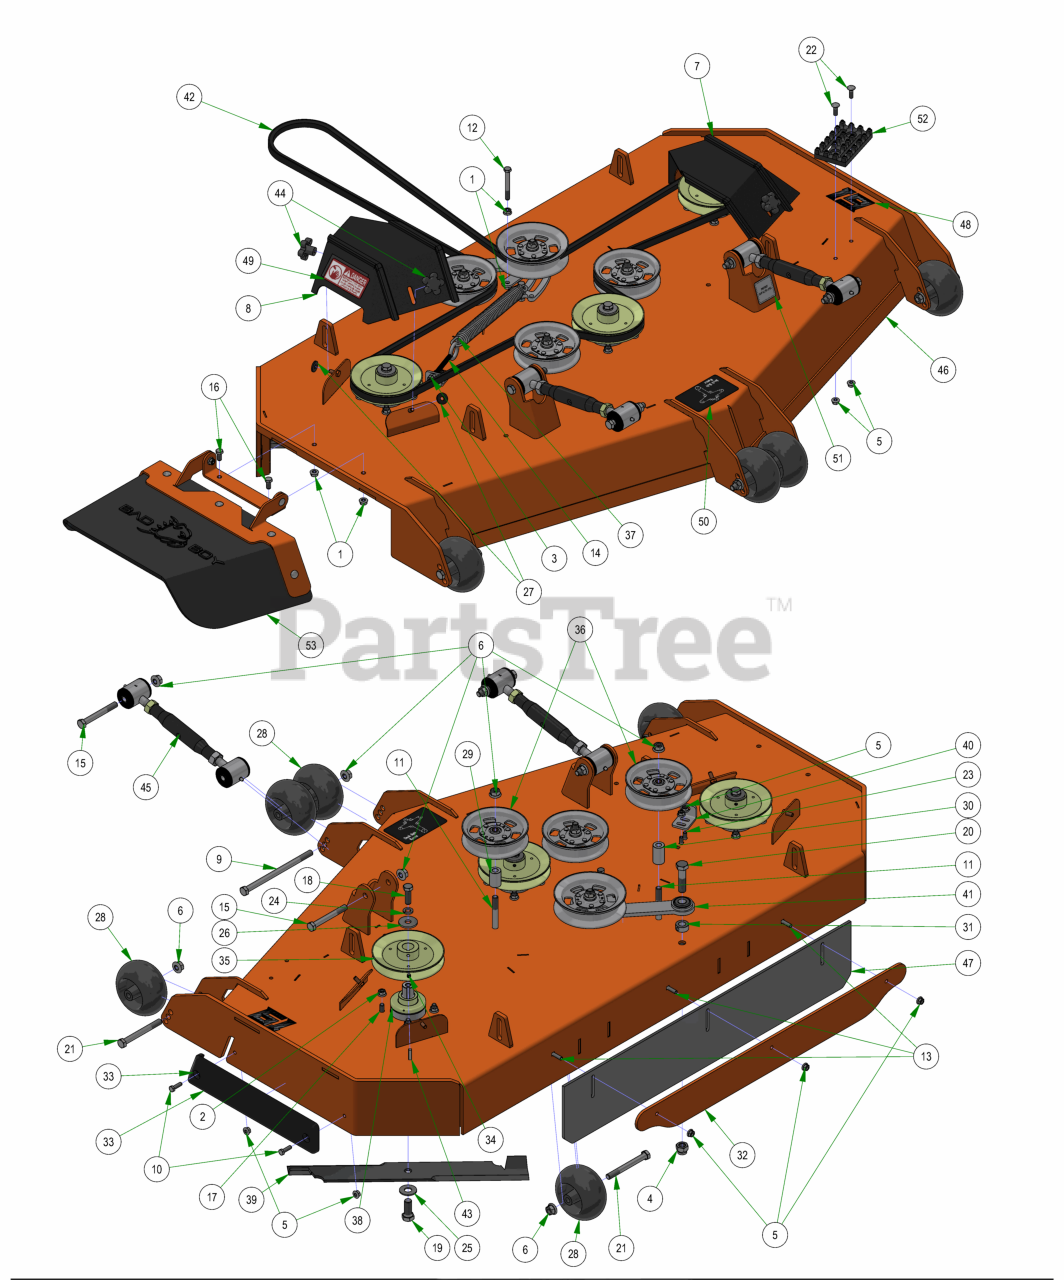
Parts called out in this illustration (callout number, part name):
1	3/8-16 HEX SERRATED FLANGE NUT HARD/ZINC
2	3/8-16 NYLON INSERT FLANGE LOCKNUT (GR.F) ZINC
3	3/8-16 HEX NUT ZINC
4	5/8-11 NYLON INSERT LOCKNUT ZINC
5	5/16-18 NYLON INSERT FLANGE LOCKNUT ZINC
6	1/2-13 NYLON INSERT FLANGE LOCKNUT ZINC
7	2019 61" Outlaw Gen2 Pulley Cover Left
8	2019 61" Outlaw Gen2 Pulley Cover Right
9	1/2-13 X 8 HEX CAP SCREW GR 5 ZINC
10	5/16-18 X 1 HEX CAP SCREW (GR.5) ZINC
11	1/2-13 X 3-1/2 HEX FLANGE BOLT (GR.8) ZINC
12	3/8-16 X 3 HEX CAP SCREW (GR.5) ZINC
13	5/16-18 X 1-1/4 CARRIAGE BOLT ZINC
14	4" 3/8-16 Eye Bolt
15	1/2-13 X 4 HEX CAP SCREW (GR.8) ZINC YELLOW
16	3/8-16 X 3/4 HEX CAP SCREW (GR.5) ZINC
17	3/8-16 X 1-1/2 HEX CAP SCREW (GR.5) ZINC
18	1/2-20 X 1-1/2 HEX CAP SCREW (GR.5) ZINC
19	5/8-18 X 1-1/2 HEX CAP SCREW (GR.8) ZINC YELLOW
20	5/8-11 X 2-1/2 HEX CAP SCREW (GR.5) ZINC
21	1/2-13 X 4-1/2 HEX CAP SCREW (GR.5) ZINC
22	5/16-18 X 1 CARRIAGE BOLT (GR.8) ZINC
23	5/16-18 X 7/8 CARRIAGE BOLT ZINC
24	1/2 SPLIT LOCKWASHER (GR.8) ZINC/YELLOW
25	5/8 USS FLAT WASHER (1-3/4" OD) GR.8 ZINC YELLOW
26	1/2 BELLEVILLE WASHER (1-5/8 OD X .140 THK) ZINC
27	.360 ID X .983 OD X .120 THICK FLAT WASHER NYLON BLACK
28	2019 Deck Wheel
29	.502 ID X .750 OD X 1.500 Long Spacer
30	1 3/4" Pulley Spacer
31	5/8 SOLID SHAFT COLLAR (W/1 SET SCREW) ZINC
32	61 Bolt in Baffle Deck v2 Stripping Plate
33	REVISED TRIM BUMPER_20180226
34	5/16-24 X 1/4 SOCKET SET SCREW (CUP PT) PLAIN
35	6 1/4" Drive Pulley
36	5-3/4 Idler Pulley
37	2019 Outlaw Gen2 Deck Spring
38	OUTLAW SPINDLE ASSEMBLY
39	61" High Lift Fusion Blade
40	2019 Deck Eye Bolt Tab
41	2019 Rebel Rogue Deck Idler
43	1/4 X 1 SQ MACHINERY KEY 1018 STL PLN
44	5/16" Knob
45	Turnbuckle Assembly (M20-2.5)
46	2019 Sloped 61" Deck
47	R Series Rubber For Deck
48	61" Deck Decal
49	Danger Decal-Spindle/Discharge
50	2019 Rebel & Rogue Deck Belt Route Decal
51	Deck Impact Patent Decal 9591803
52	Deck Step Assembly
53	2019 Outlaw Gen2 Chute Assembly
